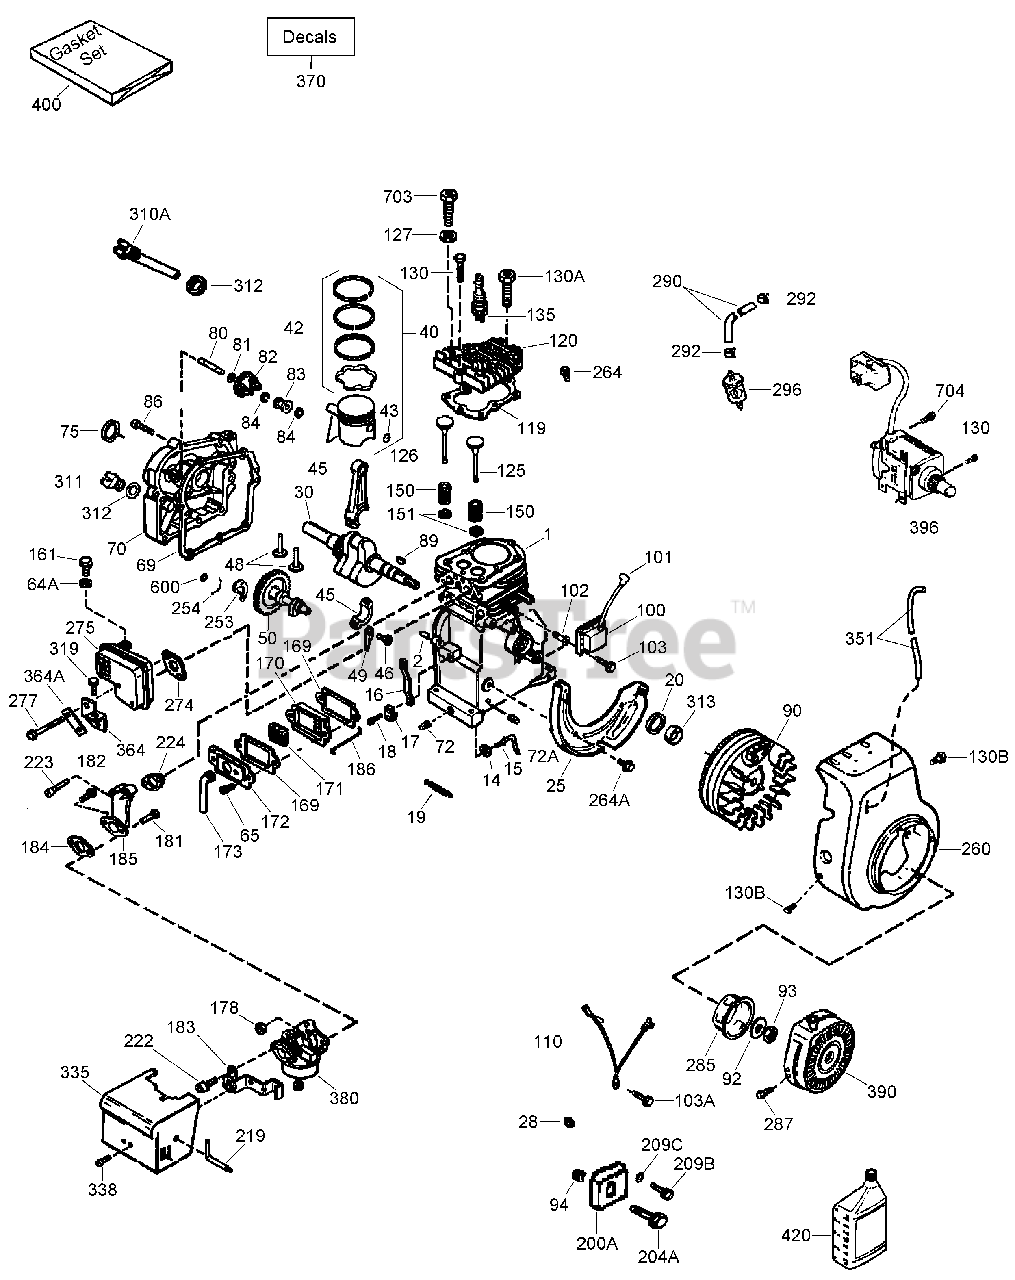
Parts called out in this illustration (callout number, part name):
150	Spring-Valve
151	Cap-Valve, Spring
161	Screw (T-30, 1/4-20x1/2)
169	Gasket-Cover, Valve
170	Body-Breather
171	Element-Breather
172	Cover-Breather
173	Tube-Breather
178	Nut and Lock Washer (1/4-28)
181	Screw (1/4-28 x 1-11/16)
182	Screw (1/4-28 x 7/8)
183	Bracket-Choke
184	Gasket (Carburetor To Intake Pipe)
185	Pipe-Intake
186	Link-Governor to Throttle
200A	Bracket-Adjusting Bolt, Governor Spring
204A	Bolt-Adjusting, R.P.M.
209B	Screw (10-24 x 9/16)
209C	Washer-Lock
219	Rod-Choke
222	Screw (10-32 X 15/32)
223	Screw (1/4-20 x 1-19/32)
224	Gasket-Intake
253	Weight-Release, Compression
254	Spring-Release, Compression
260	Housing-Blower
264	Screw (1/4-20x19/32)
264A	Screw (1/2-20x5/8)
274	Gasket-Exhaust
275	Muffler (Includes 274)
277	Screw (1/4-20 x 2-1/2)
285	Cup-Starter
287	Screw (8-32 x 21/64)
290	Line-Fuel, Low Permeation (16.0)
292	Clamp-Line, Fuel
296	Filter-Fuel (Includes 292)
310A	Dipstick (Includes 312)
311	Plug-Fill, Oil (Includes 312)
312	Gasket-Plug, Oil Fill
313	Spacer
319	Screw (10-24 x 3/8)
335	Cover-Carburetor
338	Screw (8-32 X 5/16)
351	Line-Primer
364	Bracket-Cover, Carburetor
364A	Plate-Locking
370	Decal-Tecumseh Logo for Top of Recoil Starter
380	Carburetor
390	Starter-Recoil
396	Electric Starter Motor Asm (110 Volt)
400	Gasket Set
420	Oil-Engine, S A E 5W30
600	Washer
703	Screw ( 5/16-18 x 1-1/2)
704	Screw (1/4-20 X 5/8)
999	Winter Maintenance Kit
